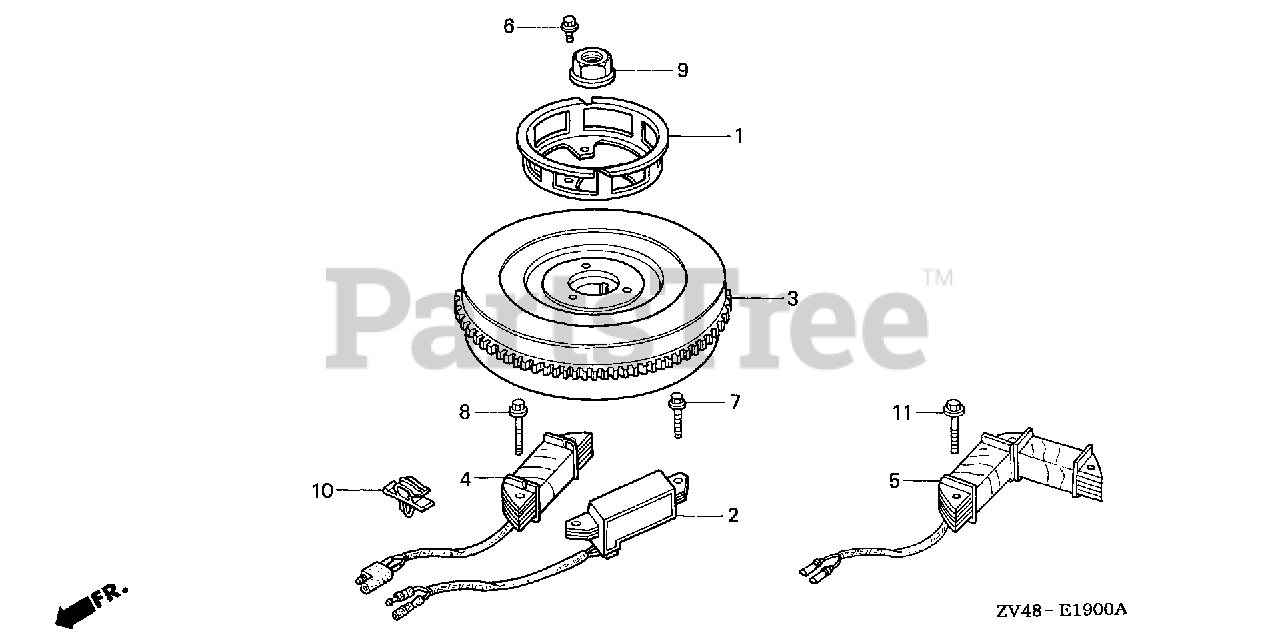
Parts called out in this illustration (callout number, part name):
1	PULLEY, STARTER
2	COIL ASSY., EXCITER
3	FLYWHEEL (SEL)
4	COIL ASSY., CHARGE (12V-6A)
5	COIL ASSY., CHARGE (12V-10A)
6	BOLT, FLANGE (6X12)
7	BOLT, FLANGE (6X25)
8	BOLT, FLANGE (6X32)
9	NUT, SPECIAL (16MM)
10	CLIP, CORD
11	BOLT, FLANGE (6X32)
